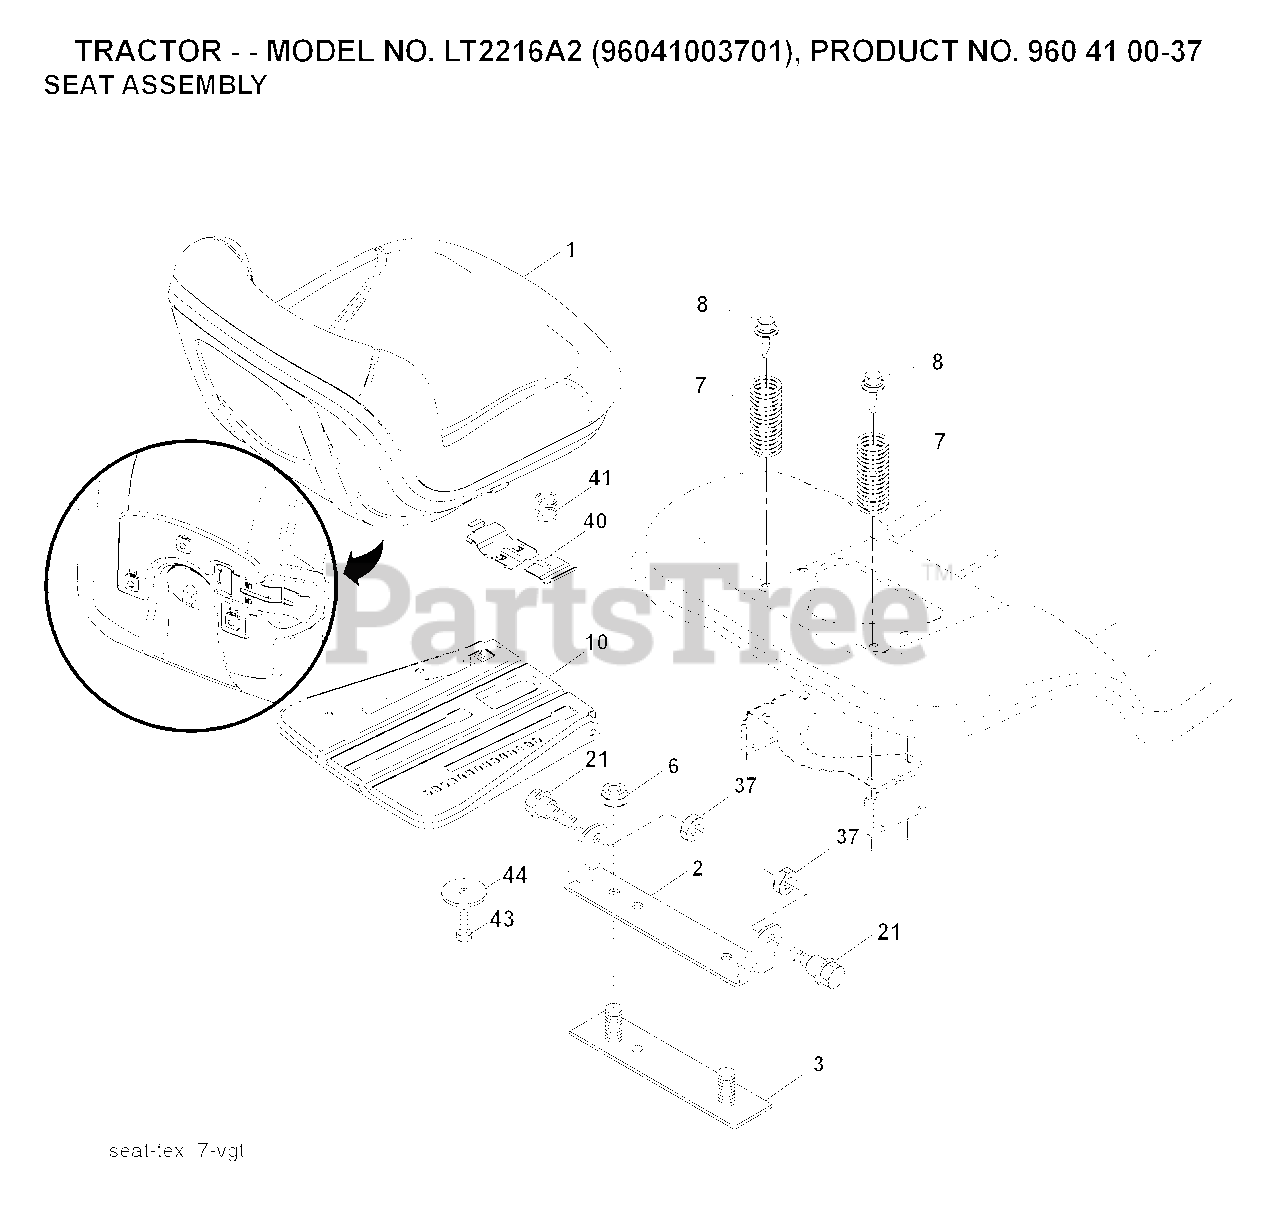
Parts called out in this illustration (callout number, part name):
1	SEAT.TG150.BLK.NLOGO.
2	BRKT.PIVOT.FENDER
6	NUT
7	SPRING COMPRESSION
8	BOLT, 5/16-18 X 1 3/4
10	PAN.ASM.SEAT.3PT
21	BOLT.SHOULDER.5/16-18
37	NUT.71038.31-18.HEX.NYLOCK
40	HANDLE.SLIDE.SEAT.TEX.BLACK
41	SPRING.LATCH.SEAT.TEX
44	WASHER 13/32 X 2-3/8 X 12GA
